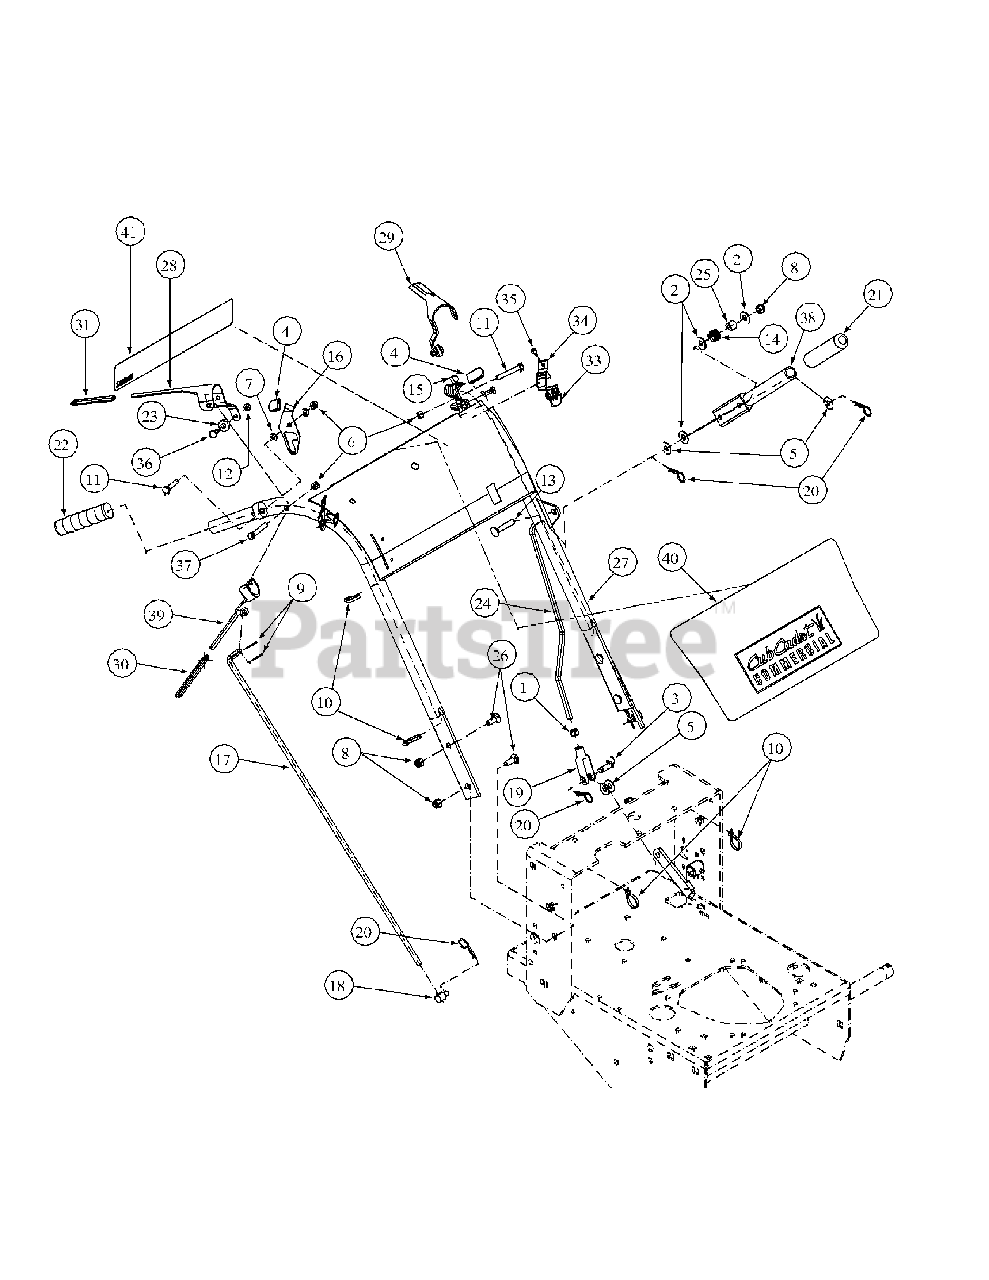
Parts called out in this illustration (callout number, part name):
1	Hex Nut, 3/8-16
2	Flat Washer, 3/8 Zinc
3	Clevis Pin, 3/8 x 1-1/8 Zinc
4	Grip, Neutral Latch, 1.25"
5	Flat Washer, 3/8 Zinc
6	Nylock Nut, 5/16-18
7	Flat Washer, 5/16 Zinc
8	Lock Nut, Nylon Insert, 3/8-16
9	Cotter Pin, 3/32 x 3/4, Zinc
10	Cable Tie, 3/16 x .05 x 7.4
11	Hex Cap Screw, 5/16-18 x 2
12	Lock Nut, Nylon Insert
13	Carriage Bolt, 3/8-16 x 2
14	Spring, .850 OD x 1
15	Neutral Latch, Left Hand
16	Neutral Latch, Right Hand
17	Steering Control Rod
18	Joint Swivel
19	Yoke, 3/8-16 Female
20	Hair Pin 3/8-1/2
21	Handle Grip, Black, 1"
22	Plastic Handle Grip, Black, 4-5/8
23	Control Rod, Hydro Spacer
24	Blade Clutch Rod
25	Spring Sleeve
26	Carriage Bolt, 3/8-16 x 2
27	Handle Assembly
28	Operator Presence Control RH
29	Operator Presence Control LH
30	Control Sleeve, Black
31	Operator Control Sleeve, Yellow
32	Harness Assembly Adapter (not show)
33	Switch Mounting Snap
34	Operator Presence Return Spring
35	Hex Index Washer Screw, 0.500
36	Shoulder Screw, .38 x .412, 1/4-28
37	Hex Cap Screw, 5/16-18, 2.00
38	Blade Clutch Lever
39	Lever Assembly Control
40	Label Commercial Mower Panel
41	Label Commercial Mower Instruction
